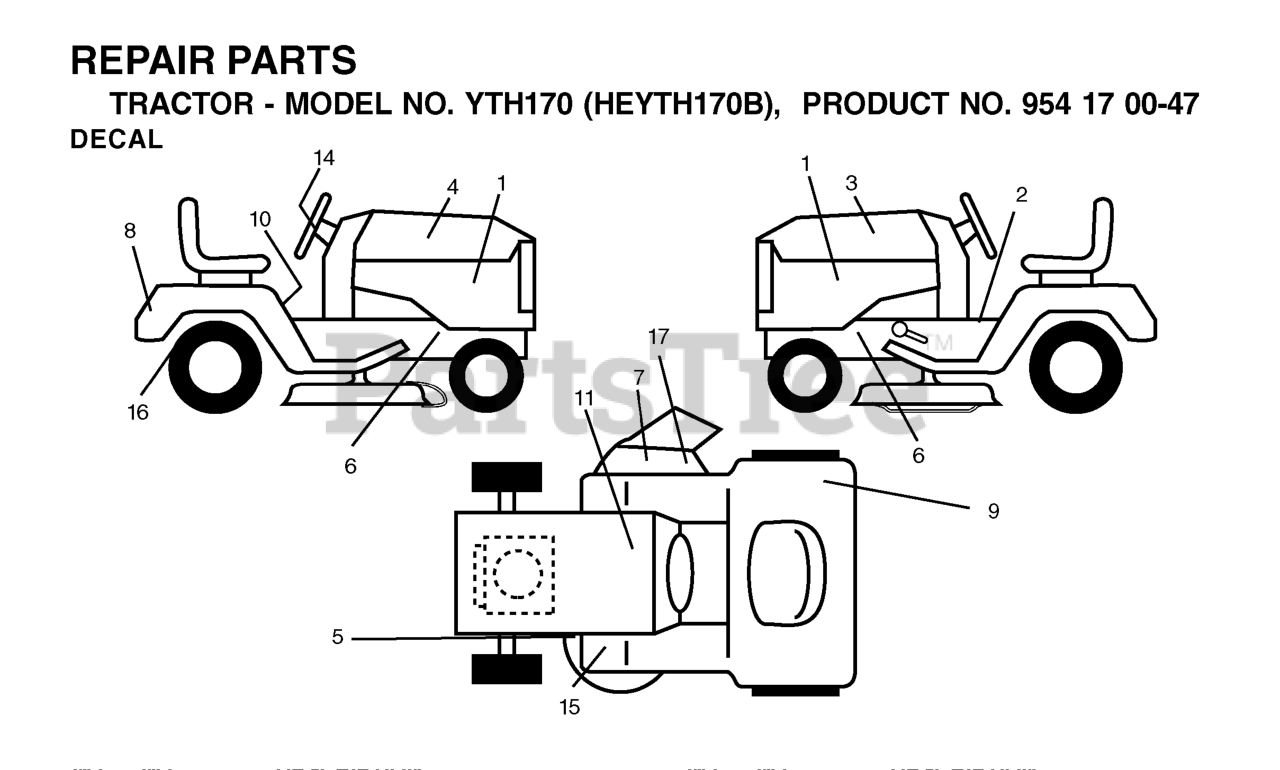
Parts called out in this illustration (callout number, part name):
1	DECAL PNL SIDE
2	DECAL PARK BRAKE
5	DECAL V BELT SCHEMATIC
7	DECAL.INTERNATIONL.CUTFINGER
8	DECAL FENDER HUSQ
9	Decal, Fender 100 DB/CE
10	DECAL READ OWNER'S MAN SYMS
11	DECAL BTRY SYMBOLS
14	DECAL.WHEEL.STEERING.HUSQ.PERM
15	DECAL
16	DECAL
17	DECAL DECK "B" 42"
